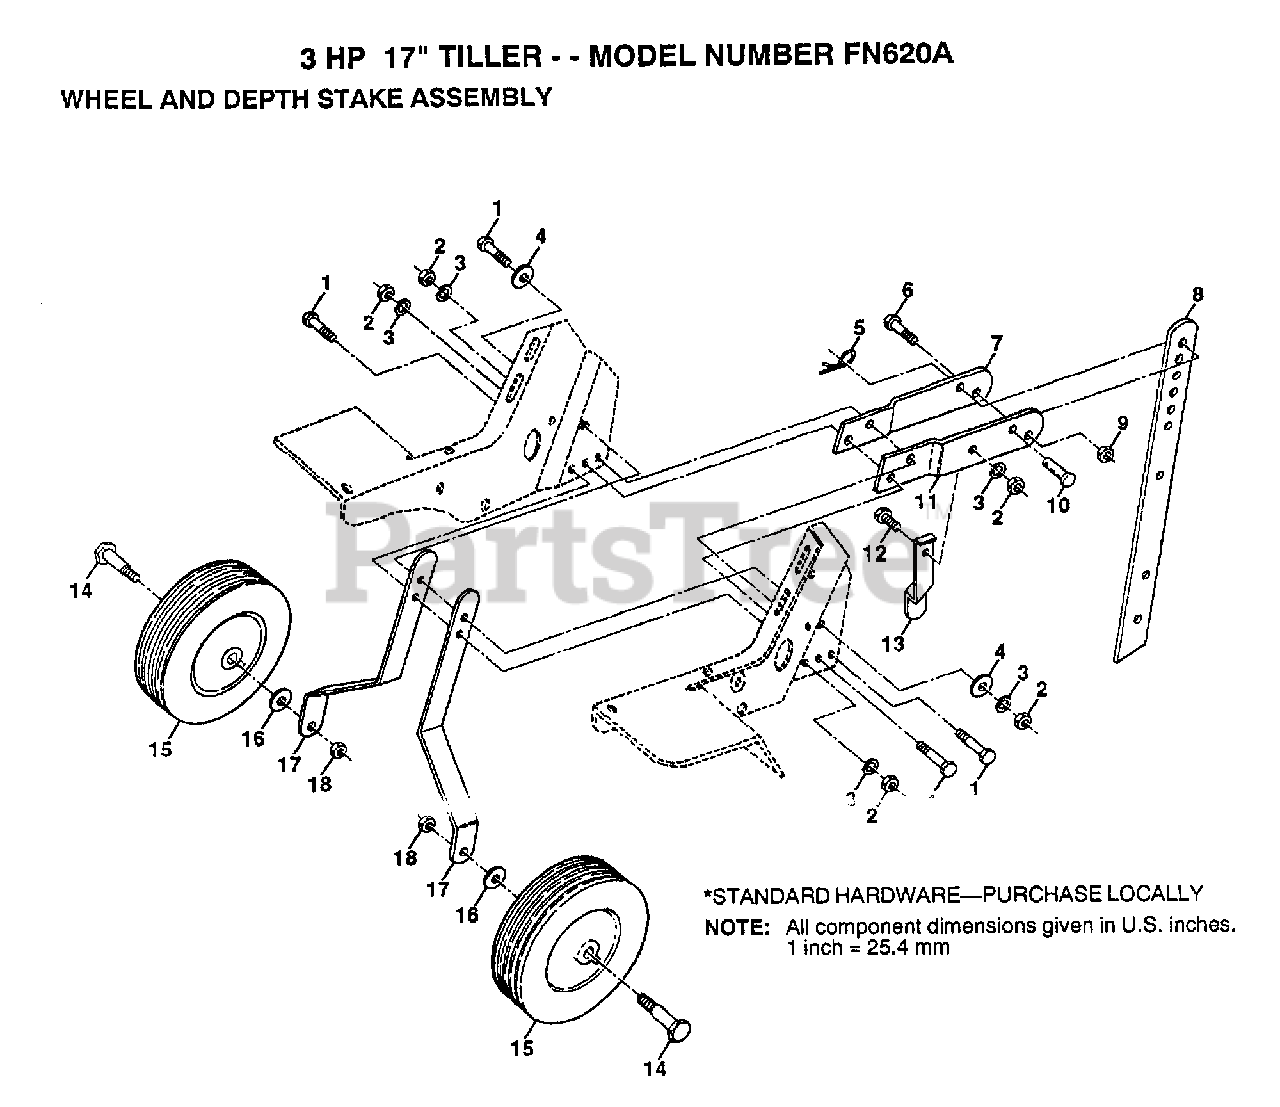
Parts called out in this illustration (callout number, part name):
2	NUT.HEX.5/16-18
3	LOCKWASHER
4	WASHER
5	SPRING.RETAINER
6	BOLT.3/8-24X1-1/2
7	STAKE.SUPT.TILLER
9	GRIPCO NUT
10	DRILLED RIVET RT
12	BOLT
13	STAKE SPRING CT
14	BOLT SHOULDER
16	WASHER
